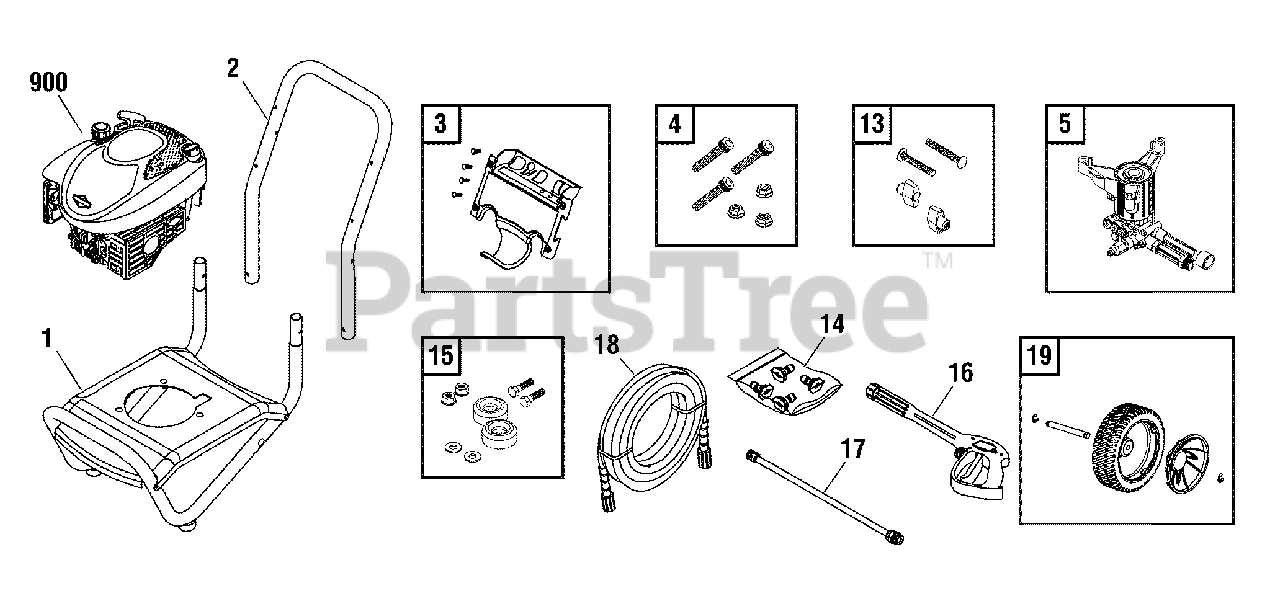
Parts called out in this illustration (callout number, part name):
2	HANDLE
3	ASSEMBLY, Billboard w/Decal & CLIPS
4	KIT, Pump Mounting Hardware
5	PUMP
13	KIT, Handle Connector
15	KIT, Vibration Mount
16	GUN
17	WAND, QC
18	HOSE
19	KIT, Wheel
900	* ENGINE
